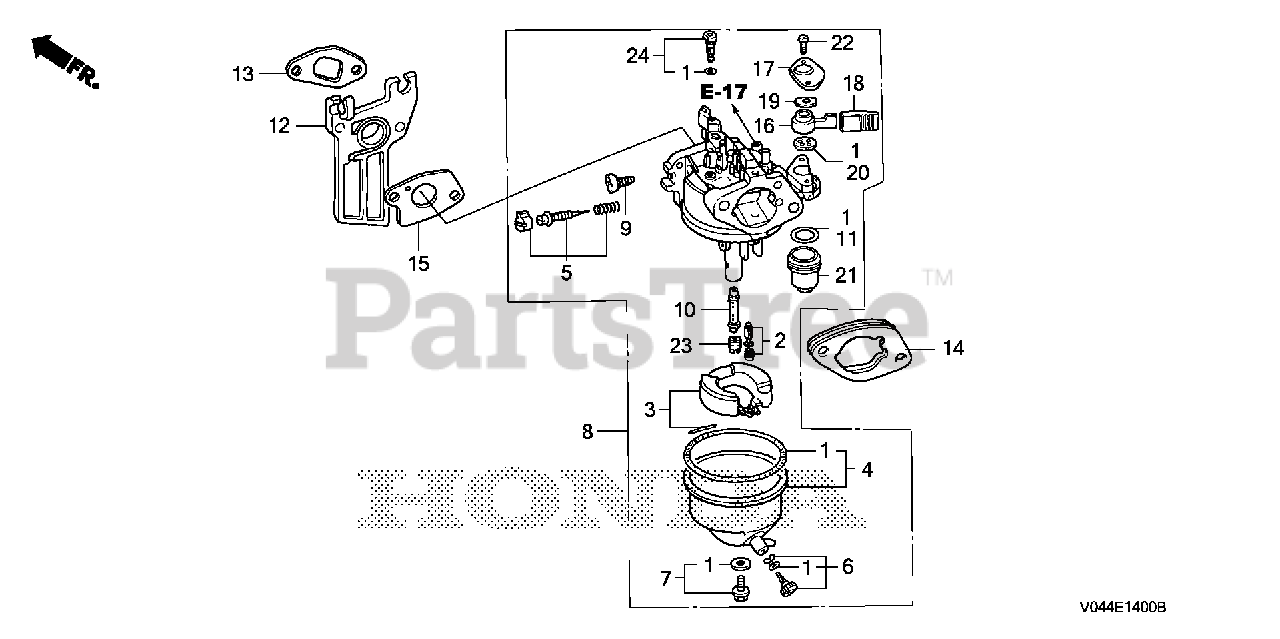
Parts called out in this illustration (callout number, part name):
1	GASKET SET
2	VALVE SET, FLOAT (SEAT NOT INCLUDED)
4	CHAMBER SET, FLOAT
5	SCREW SET, PILOT
6	SCREW SET, DRAIN
7	SCREW SET
8	CARBURETOR ASSY. (BE64Q A)
9	SCREW, THROTTLE STOP
10	NOZZLE, MAIN
11	GASKET, FUEL STRAINER CUP
12	INSULATOR, CARBURETOR
13	GASKET, INSULATOR
14	SPACER, CARBURETOR
15	GASKET, CARBURETOR
16	LEVER, PETCOCK
17	PLATE, LEVER SETTING
18	CAP, LEVER
19	SPRING, PETCOCK LEVER
20	GASKET, PETCOCK
21	CUP, FUEL STRAINER
22	SCREW, PAN (3X6)
23	JET, MAIN (#72)
23	JET, MAIN (#75)
23	JET, MAIN (#70)
24	JET SET, PILOT (#45)
